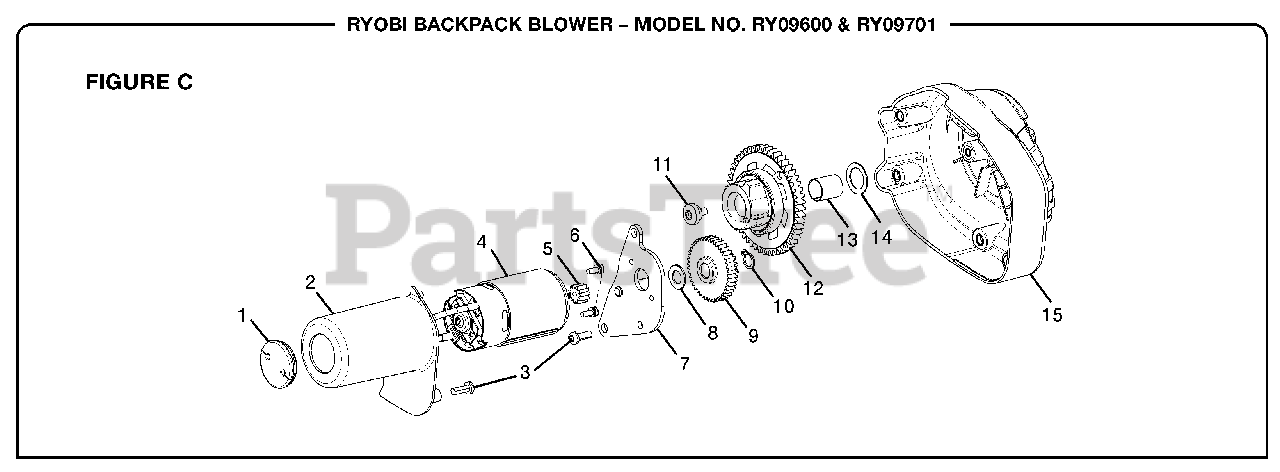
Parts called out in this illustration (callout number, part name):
2	Motor Cover
3	Screw (M4 x 11 mm)
6	Screw (M3 x 8 mm)
7	Bracket and Shaft Assembly
8	Thrust Washer
9	Pulley and Gear
10	Retaining Ring
11	Screw (M4 x 6 mm)
12	Final Start Gear and Pawl Assembly
15	Rear Cover
